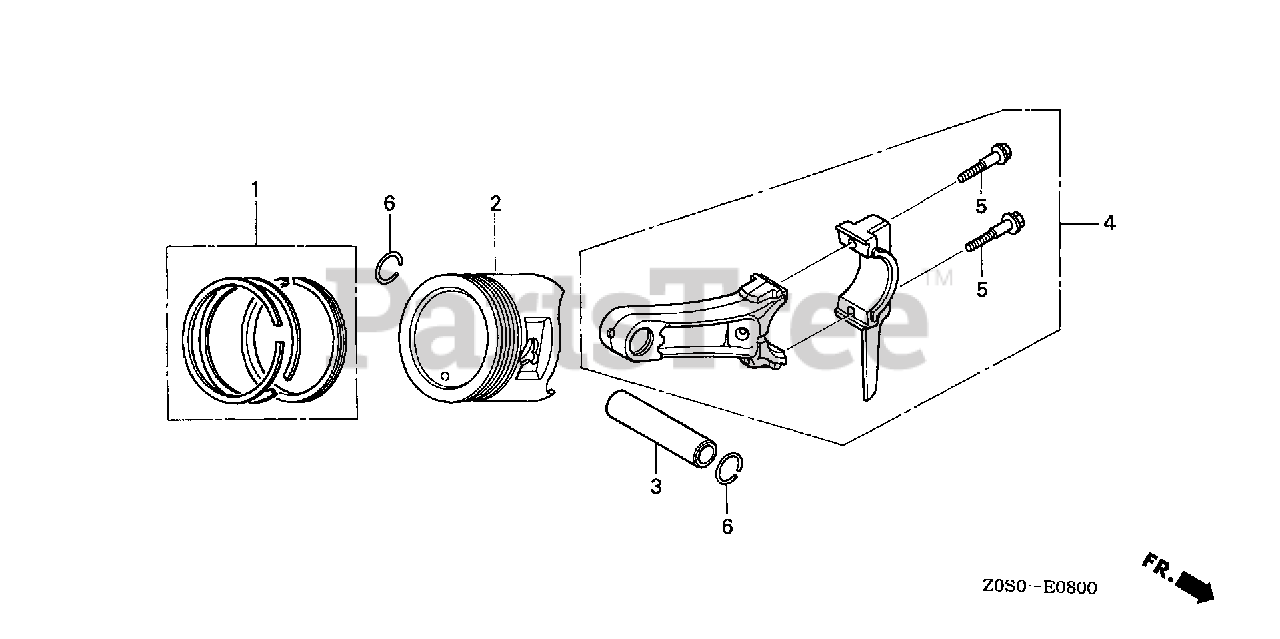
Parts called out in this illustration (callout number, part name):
1	RING SET, PISTON (STD) (TPR)
1	RING SET, PISTON (STD) (RIKEN)
2	PISTON (STD)
3	PIN, PISTON
4	ROD ASSY., CONNECTING
4	CONN ROD ASSY.
5	BOLT, CONNECTING ROD
6	CLIP, PISTON PIN (13MM)
